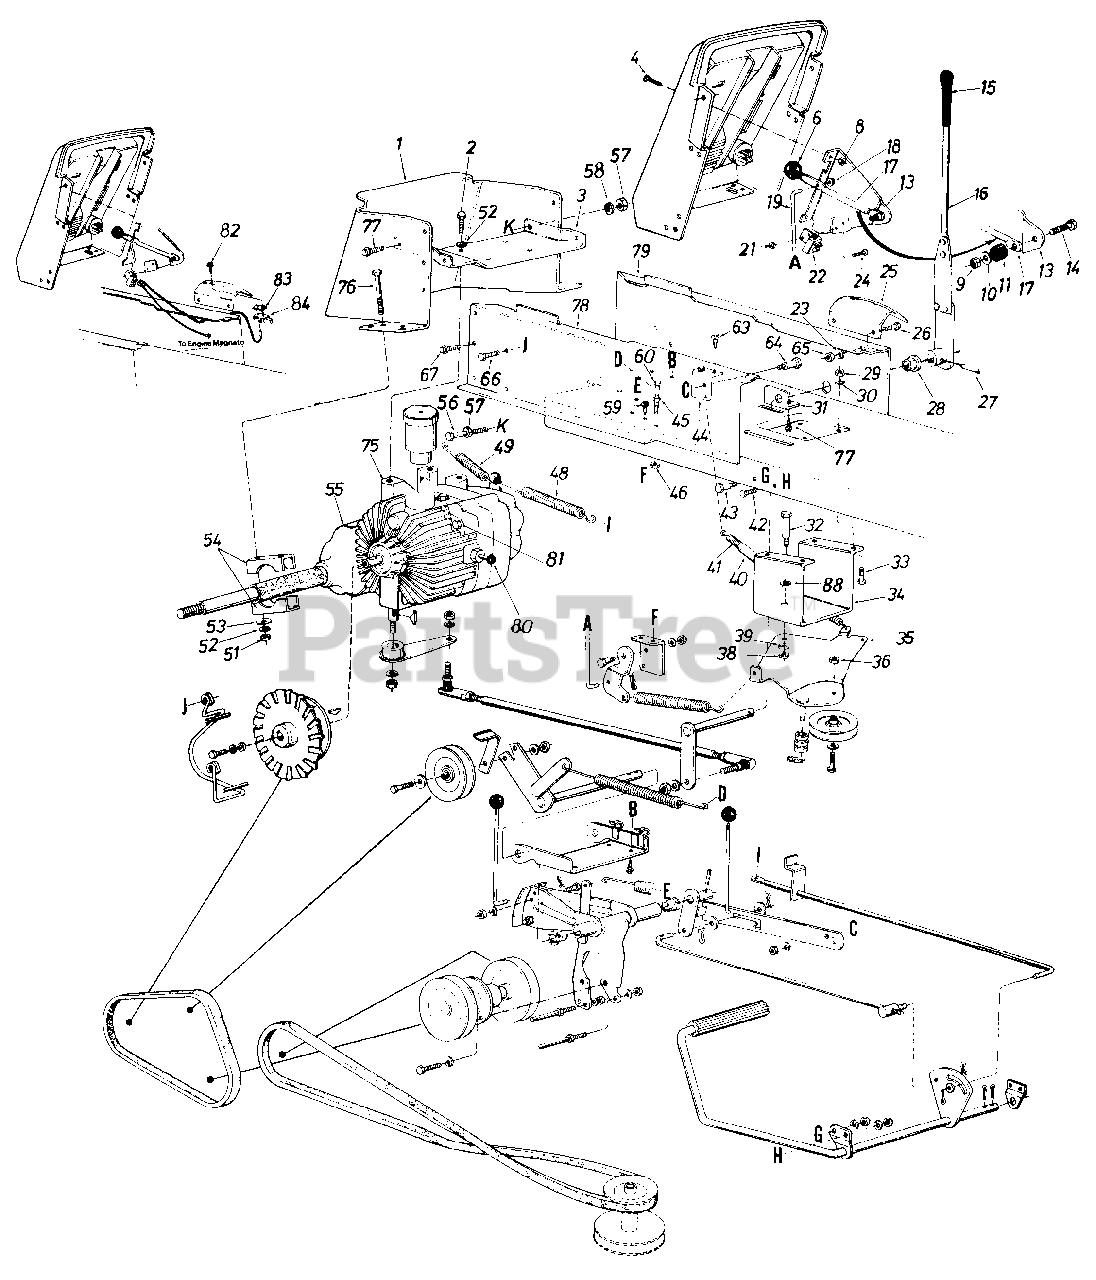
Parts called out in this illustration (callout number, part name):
1	Hitch Plate
2	Hex Bolt 3/8-16 x .75" Lg.
3	Rear Axle Support Brkt.
4	Truss Mach. Scr. 1/4-20 x .50" Lg.*
6	Knob-Blade Clutch
8	Hex Sems Nut 1/4-20 Thd.
9	Hex Cent. L-Nut 1/4-20 Thd.
10	Fl-Wash. .28" I.D. x .741' O.D. x .063
11	Rubber Wash. .33" I.D. x .87" O.D. x.30
13	Deck Clutch Cont. Brkt.
14	Hex Bolt 1/4-20 x 1.25" Lg.
16	Control Arm Ass'y.
17	Blade Clutch Lever
18	Push Nut 1/4" O.D. Rod
19	Deck Control Rod
21	Hex Nut #10-24 Thd.
22	Safety Switch
23	L-Wash. 5116" I.D.*
24	Truss Mach. Scr. #10-24 x .50" Lg.
25	Speed Control Bracket
26	Hex Bolt 5/16-18 x .62" Lg.
27	Spring Pin Spiral 1/4" Dia. x 1.5" Lg.
28	Hex Flange Brg.
29	Hex Nut 5/16-18 Thd.
30	L-Wash. 5116" I.D.
31	Speed Control Shaft Brkt.
32	Shld. Scr. .437" Dia. x .162" Lg.
33	Hex Bolt 5/16-18 x 1.00" Lg.
34	Idler Support Brkt.
35	Idler Brkt. Ass'y.
36	Hex L-Nut 3/8-16 Thd.
38	Hex Nut 5/16-18 Thd.
39	L-Wash. 5/16" I.D.
40	Convoluted Conduit .50" I.D.
41	Ext. Spring .50" O.D. x 6.37"
42	Hex Bolt 3/8-16 x .62" Lg.
43	Shld. Scr. .50" Dia. x .395" Lg. (3/8-16)
44	Parking Brake Cam Mtg. Brkt.
45	Hex Nut 5/16-28 Thd.*
46	Hex L-Nut 5/16-18 Thd.
48	Brake Tension Spring
49	Ext. Spring-Brake Return
51	Hex Nut 3/8-16 Thd.*
52	L-Wash. 3/8" I.D.*
53	Fl-Wash. .390" I.D. x 1.00" O.D. x .125" Thk.
54	Rear Axle Bracket
55	Transaxle
56	Hex Bolt 1/4-20 x 2" Lg.*
57	Hex Nut 1/4-20 Thd.*
58	L-Wash. 1/4" I.D.*
59	Hex Wash. Hd. Self-Tap Scr. 1/4-20 x .50" Lg.
60	Hex Bolt 5/16-18 x 1.50" Lg.
63	Hex Wash. Hd. Self-Tap Scr. 1/4-20 x .50" Lg.
64	Shld. Scr. .437" Dia. x .162' Lg.
65	Hex Nut 5/16-18 Thd.*
66	Hex Wash. Hd. Scr. 3/8-16 x .50" Lg.*
67	Hex Wash. Hd. Self-Tap Scr. 5/16-18 x .75" Lg.
75	Hydrostatic Pump Comp.
76	Hex Bolt 3/8-16 x 3.5" Lg.
77	Hex AB-Tap Scr. 5/16 x .75" Lg.
78	Side Panel Upper Frame R.H.
79	Side Panel Upper Frame L.H.
81	Socket Hd. Bolt 3/8-16 x 2.75" Lg.
82	Hex Wash. Hd. Scr. #8 x .50" Lg.
83	Insulator Nut Plate
84	Spring Switch
88	Wave Washer
